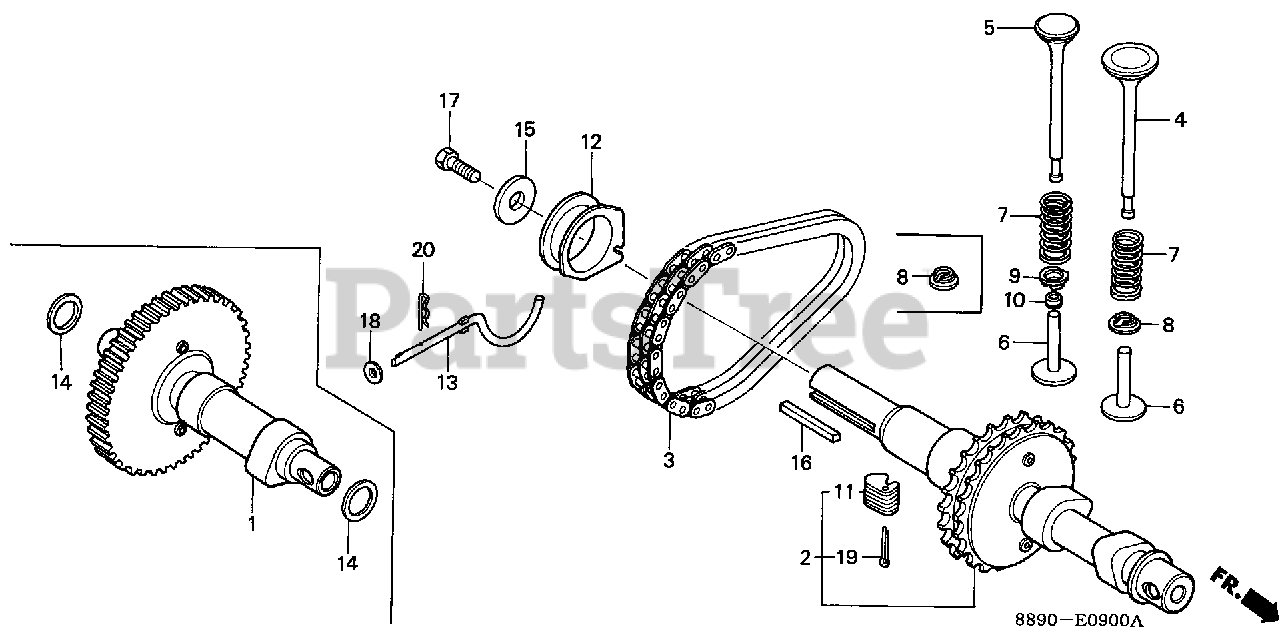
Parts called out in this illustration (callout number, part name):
1	CAMSHAFT ASSY.
4	VALVE, IN.
5	VALVE, EX. (NOT AVAILABLE)
5	VALVE, EX.
6	LIFTER, VALVE (45.89MM)
6	LIFTER, VALVE (46.04MM)
6	LIFTER, VALVE (46.19MM)
6	LIFTER, VALVE (46.34MM)
7	SPRING, VALVE (NOT AVAILABLE)
8	RETAINER, VALVE SPRING
9	RETAINER, VALVE SPRING
10	ROTATOR, EX. VALVE (NOT AVAILABLE)
11	WEIGHT, GOVERNOR
12	SLIDER, GOVERNOR
13	SHAFT, GOVERNOR ARM
14	WASHER, THRUST (18MM)
18	WASHER, PLAIN (6MM)
19	PIN, SPLIT (3.0X25)
19	PIN, SPLIT (3.0X45)
20	PIN, LOCK (10MM)
